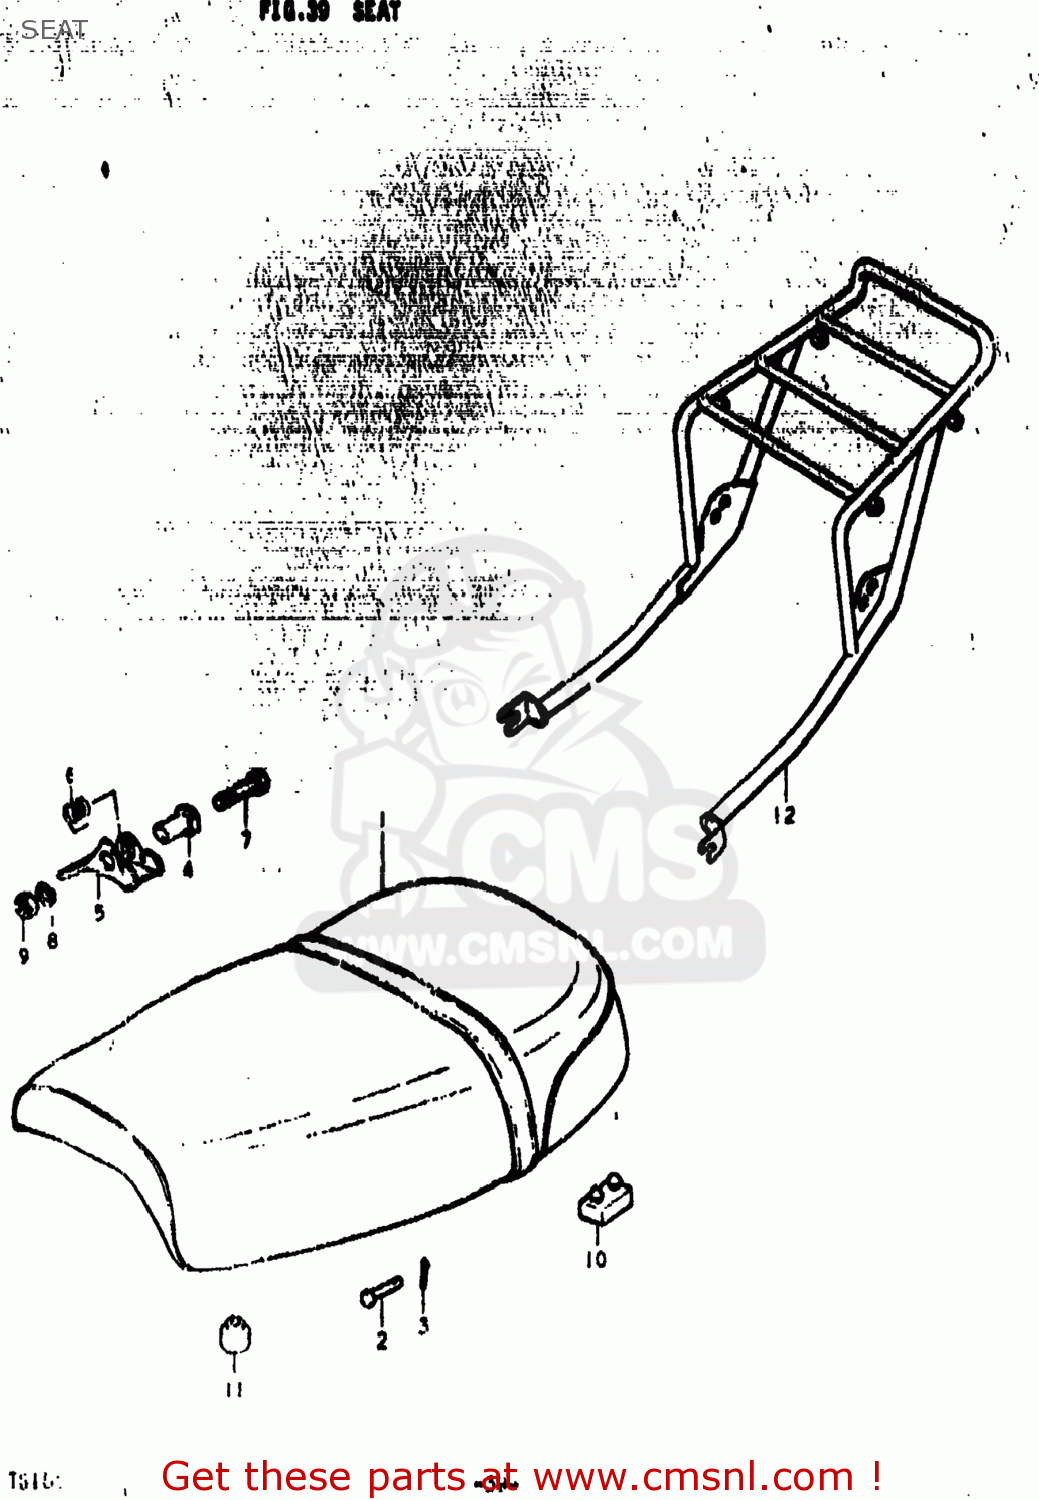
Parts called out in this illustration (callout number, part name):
1	SEAT ASSEMBLY
2	PIN
3	COTTER PIN
4	STRIKER,SEAT LOCK
5	STRIKER,SEAT LOCK
6	SPRING
7	BOLT 8X45
8	LOCK WASHER
9	NUT
10	CUSHION
11	CUSHION(11.5X22X20)
12	CARRIER
